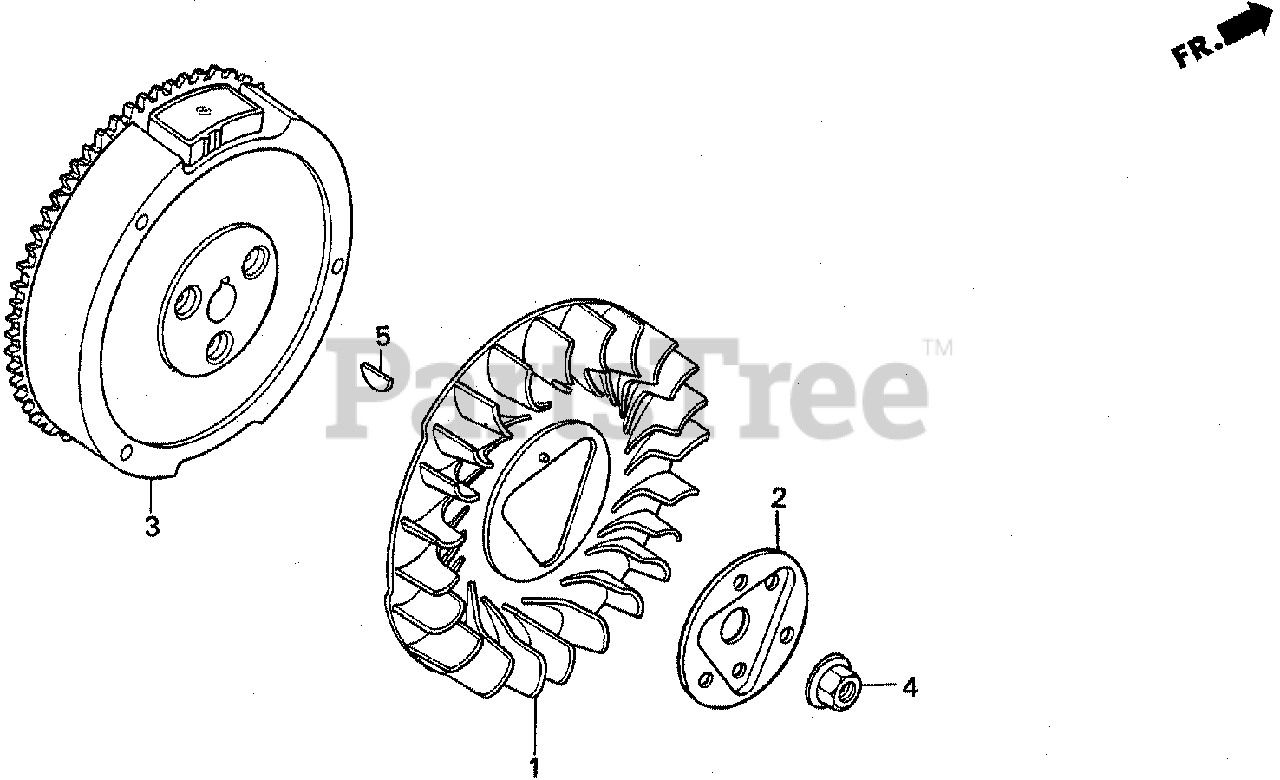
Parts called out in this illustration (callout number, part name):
1	FAN, COOLING
2	PLATE, COOLING FAN SETTING
3	FLYWHEEL (SEL-LAMP)
4	NUT, SPECIAL (16MM)
5	KEY, SPECIAL WOODRUFF (25X18)
